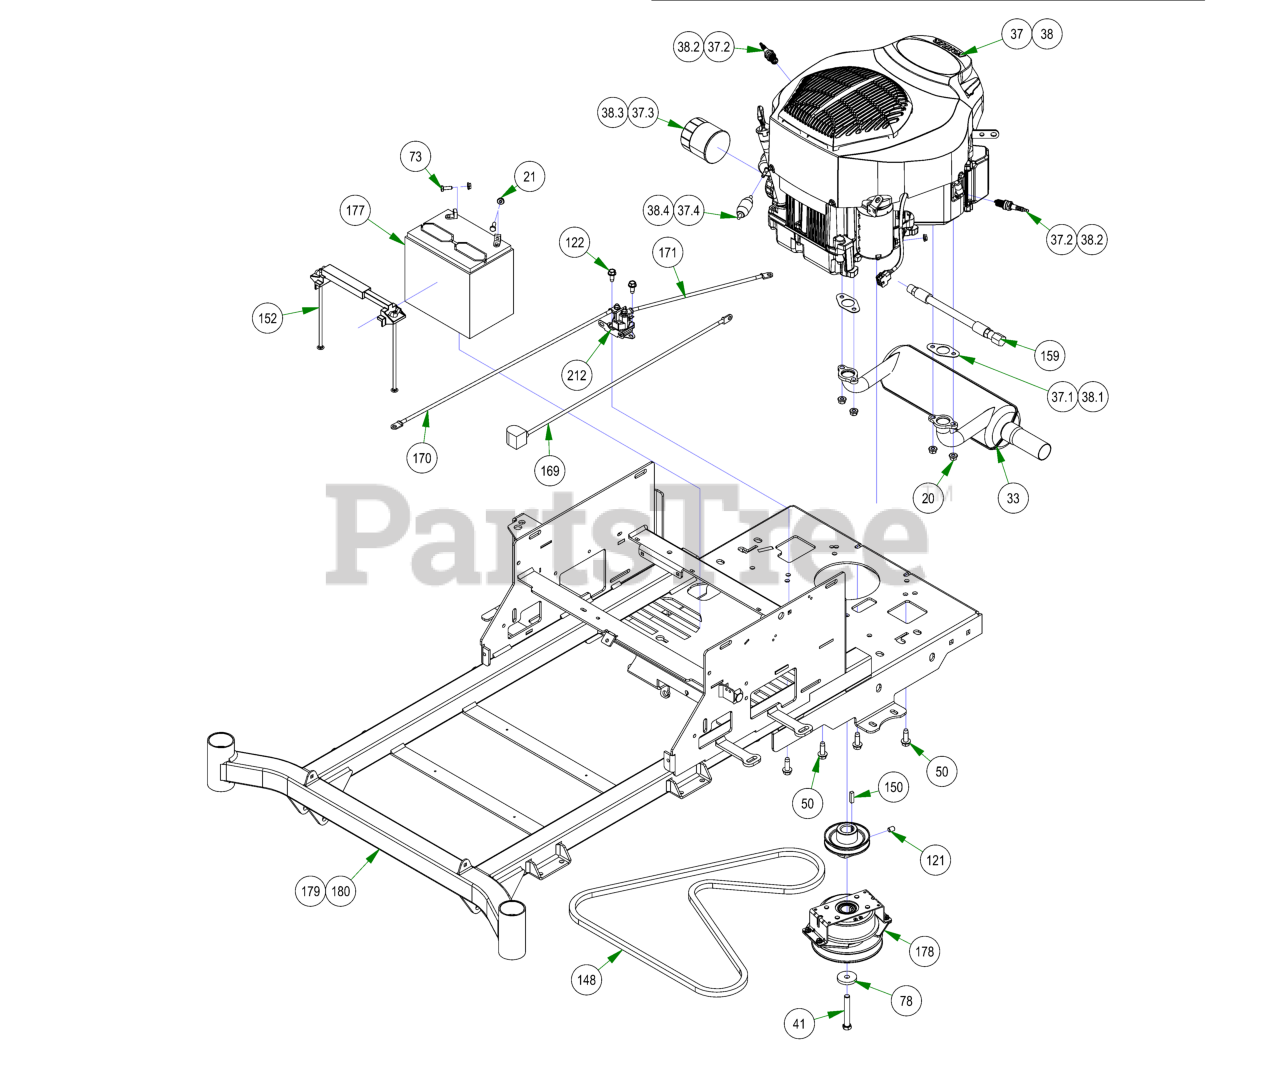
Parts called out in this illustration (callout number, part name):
20	M8 Nut Connects the 015-1012-00 and the 015-8240-00
21	1/4-20 HEX SERRATED FLANGE NUT HARD/ZINC
33	Kohler Muffler
37	25hp Kohler 2014 MZ-KT740-3048
37.1	Exhaust Gasket
37.2	Spark Plug
37.3	25 HP Kohler Oil Filter ZT?MZ
37.4	Universal Inline Fuel Filter
38	22 Kohler MZ/Magnum-KT725-3035
38.1	Exhaust Gasket
38.2	Spark Plug
38.3	25 HP Kohler Oil Filter ZT?MZ
38.4	Universal Inline Fuel Filter
41	7/16-20x3” Hex Bolt GR 8 W/ Patch
50	3/8-16 X 1-1/8HEX WASHER UNSLOT SERRATED (TRI-LOB) TRS
73	1/4-20 X 3/4 HEX CAP SCREW (GR.5) ZINC
78	CLUTCH WASHER
121	3/8-16 X 1/2 SOCKET SET SCREW (CUP PT) PLAIN
122	5/16-18 X 3/4HEX WASHER SLOT (F) TCS ZINC
126	3-3/4" Motor Pulley
150	1/4 X 1 SQ MACHINERY KEY 1018 STL PLN
152	Hold Down Assembly
159	Oil drain Hose
169	24 inch Black Cable – MZ/ZT
170	24" Red Battery Cable
171	12 in red battery cable
177	SP-35 Battery
179	2022 MZ/ZT 54"-60" Frame
180	2022 MZ/ZT 42"-48" Frame
